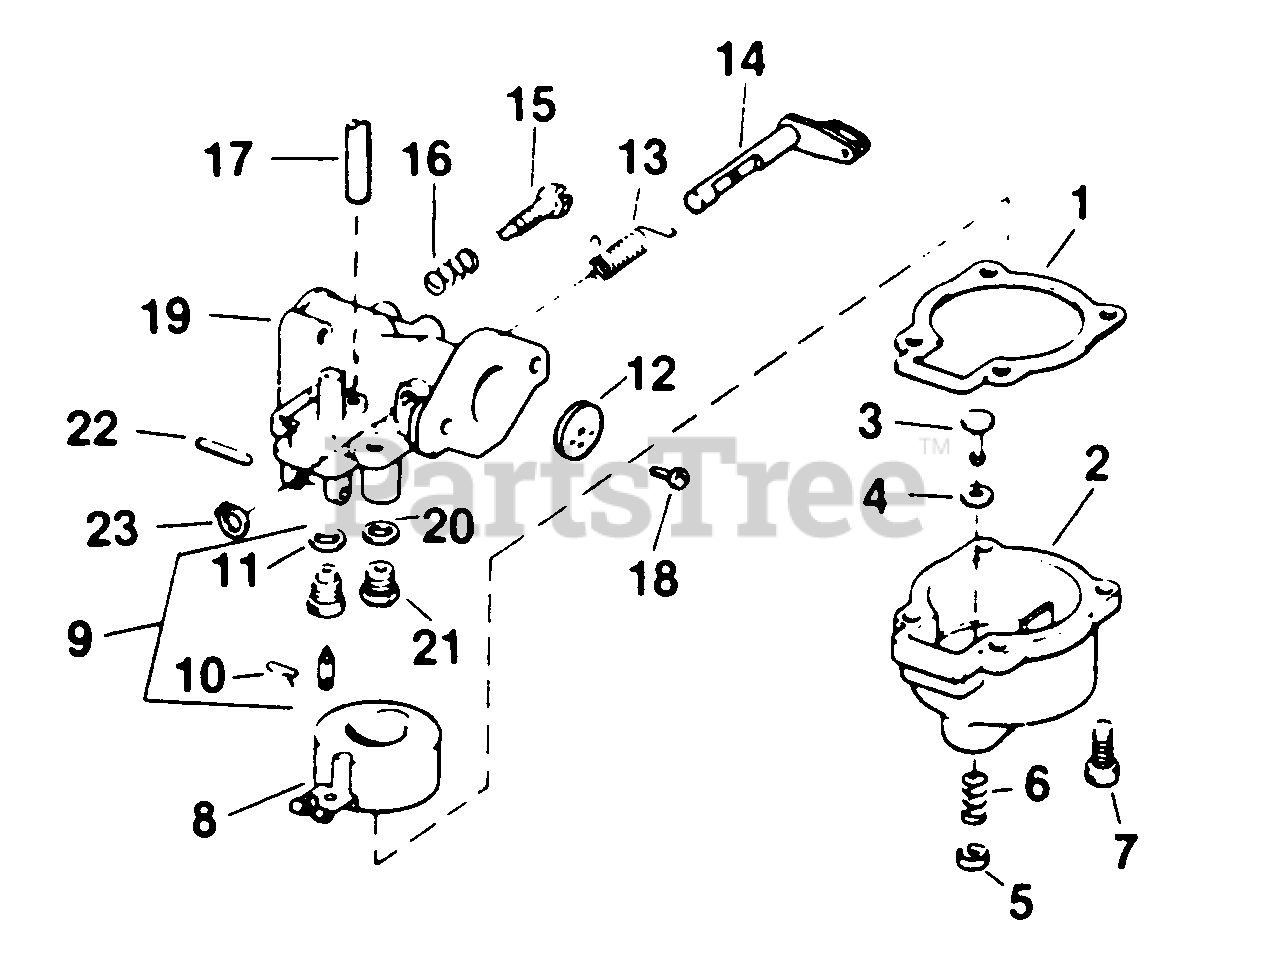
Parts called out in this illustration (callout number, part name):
1	Gasket
2	Float Chamber & Dump Valve Assy.
3	Valve Stem
4	Valve Seat
5	Valve Keeper
6	Valve Spring
8	Float & Arm Assy.
9	Float Valve & Seat Assy.
10	Clip
17	Fuel Hose
19	Carburetor Body Assy.
22	Float Pin
23	Grip Ring
